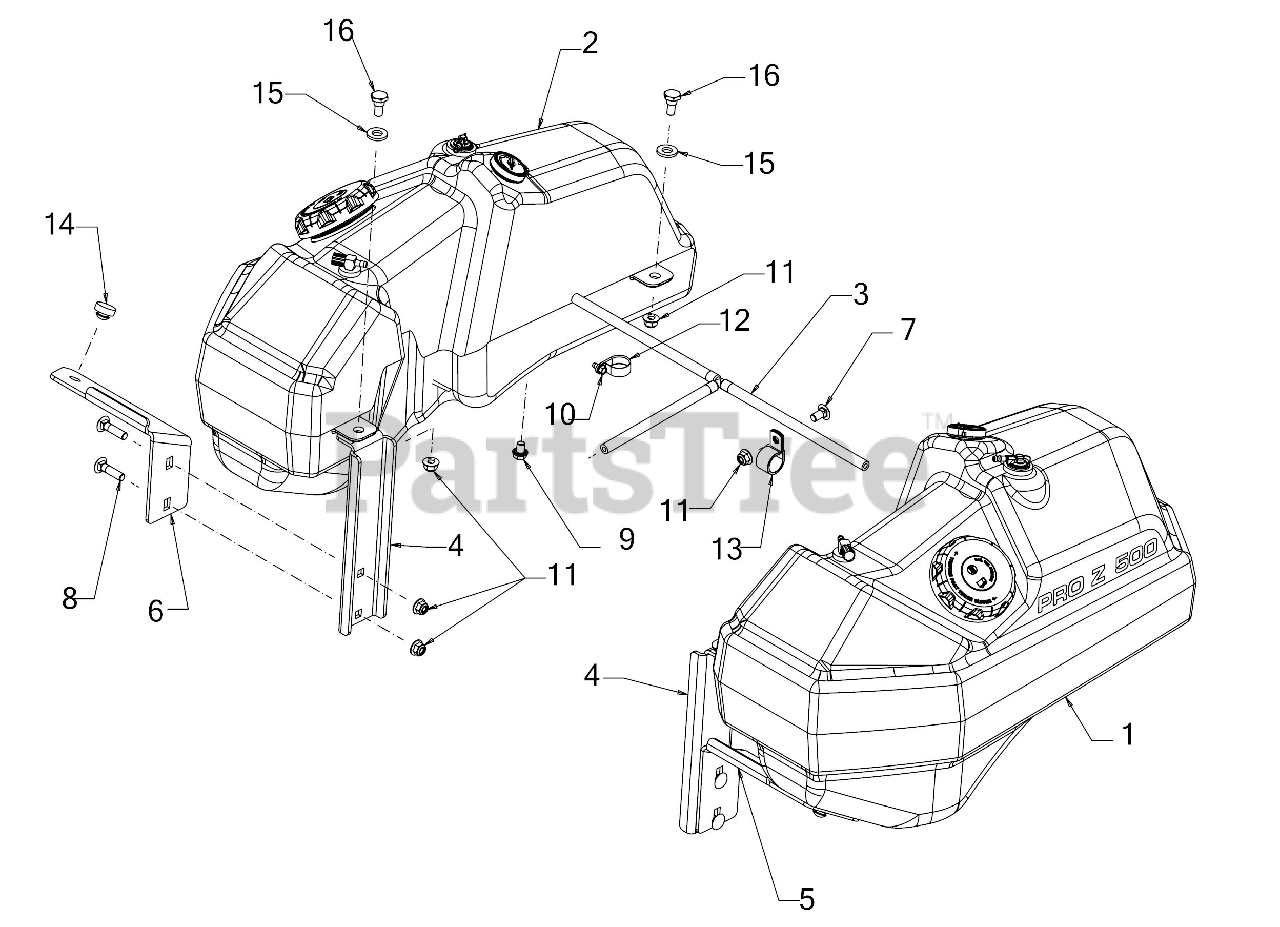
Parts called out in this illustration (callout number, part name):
1	FUEL TANK ASSEMBLY (RH) 7.25 GAL
2	FUEL TANK ASSEMBLY (LH) 7.25 GAL
3	FUEL LINE ASSEMBLY
4	FUEL TANK MOUNTING BRACKET
5	FUEL TANK MOUNTING BRACKET (RH)
6	FUEL TANK MOUNTING BRACKET (LH)
7	CARRIAGE BOLT 3/8-16 x .750 GR5
8	CARRIAGE BOLT 3/8-16 x 1.50
9	SCREW 3/8-16 x .500 GR5
10	SCREW 1/4-20 X.500
12	DRAIN HOSE CLAMP
13	HOSE CLAMP 1.0"
14	RUBBER BUMPER 1.000 x .313
15	FLAT WASHER .510 x 1.000 x .125
16	SHOULDER SCREW .498 DIA x .340
